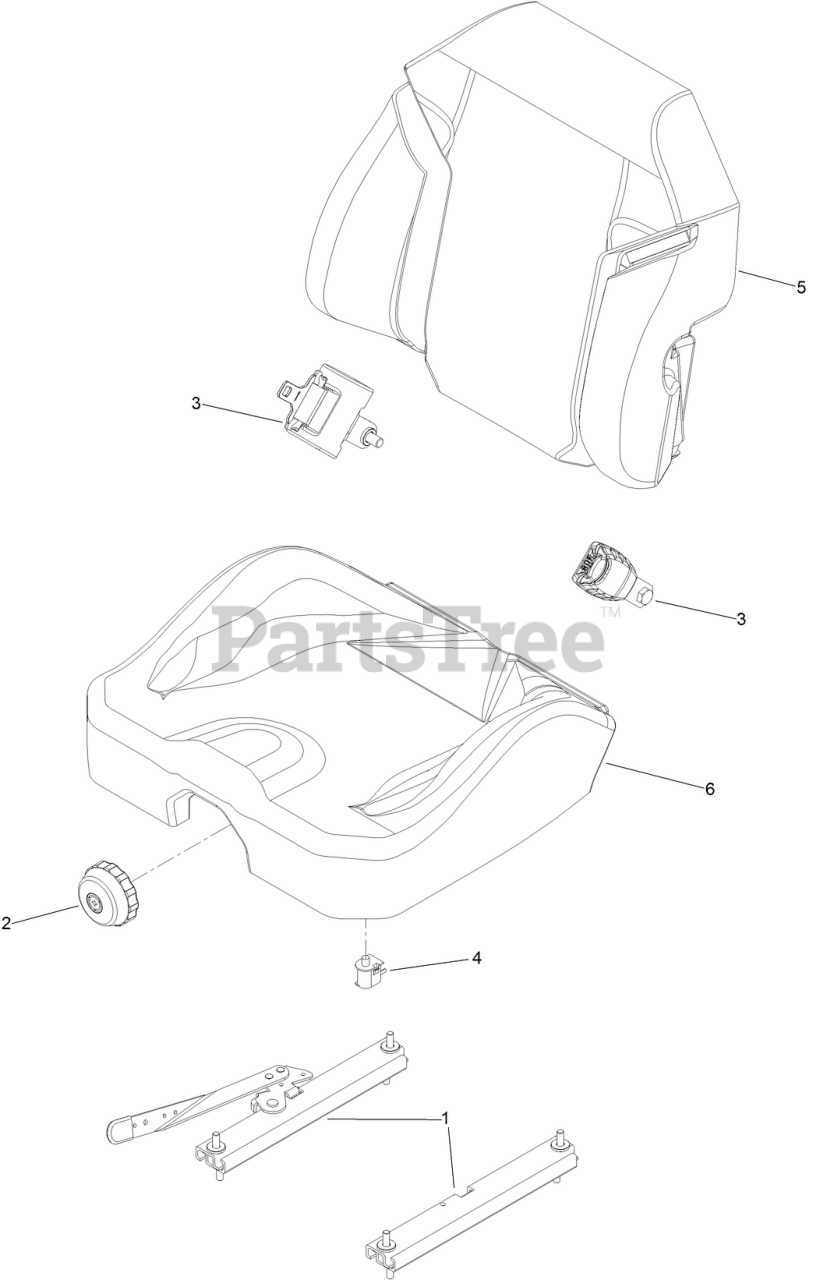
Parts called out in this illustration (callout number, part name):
1	TRACKS-4" TRAVEL
2	KNOB-ADJUSTER
3	KIT-SEAT BELT
4	SWITCH-BAIL
5	COVER-BACK, SEAT
6	COVER-BOTTOM, SUSPENSION SEAT
